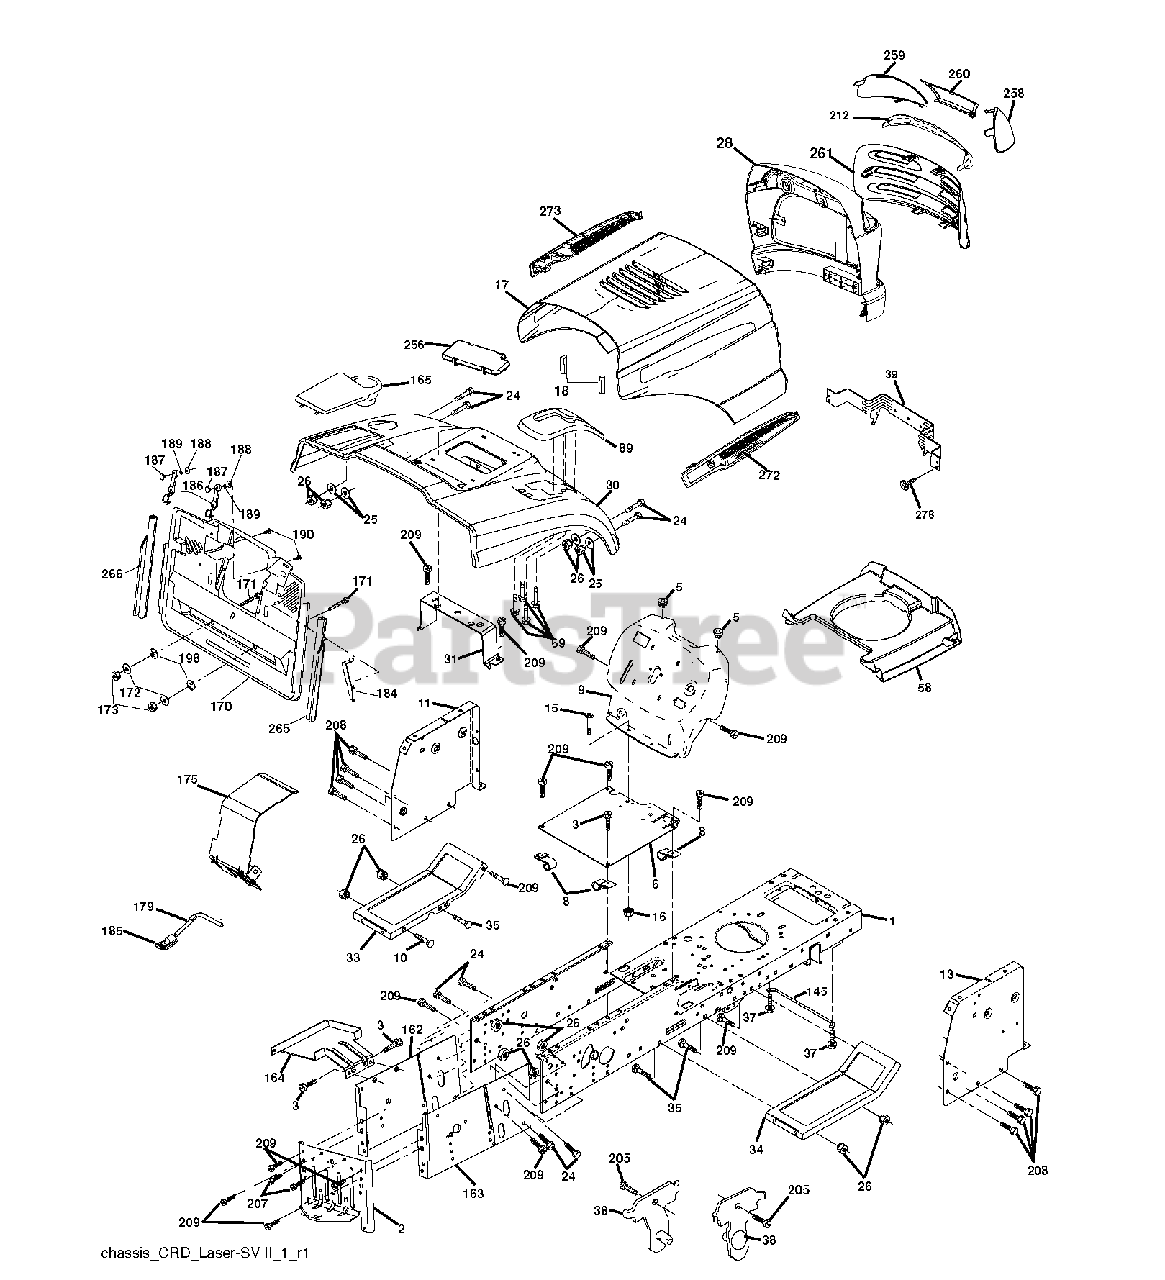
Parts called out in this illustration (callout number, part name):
1	CHASSIS
3	SCREW 3/8-16X3/4
5	BUMPER.RUBBER.HOOD
8	CLIP,INSULATOR
10	BOLT D
11	PANEL.DASH.LH.LTX
13	PANEL ASM, DASH RH
16	NUT
18	BUMPER.HOOD.LARGE.1.75"
24	BOLT
25	WASHER
26	NUT
31	BRACKET SUPPORT FENDER
35	BOLT
37	SCREW LT
39	BRACKET PIVOT
69	SCREW.HI-LO.CONSOLE
145	ROD.PIVOT.HOOD
164	SUPPORT
171	BOLT
172	WASHER
186	LATCH ASSY
187	WELDNUT
189	LOCKWASHER
190	SCREW
205	SCREW LT
207	SCREW, 5/16-18 X 1/2
208	SCREW 3/8-16X1/2
209	SCREW, 3/8-16X3/4
278	SCREW.#10 X 0.750.BOS THREAD
